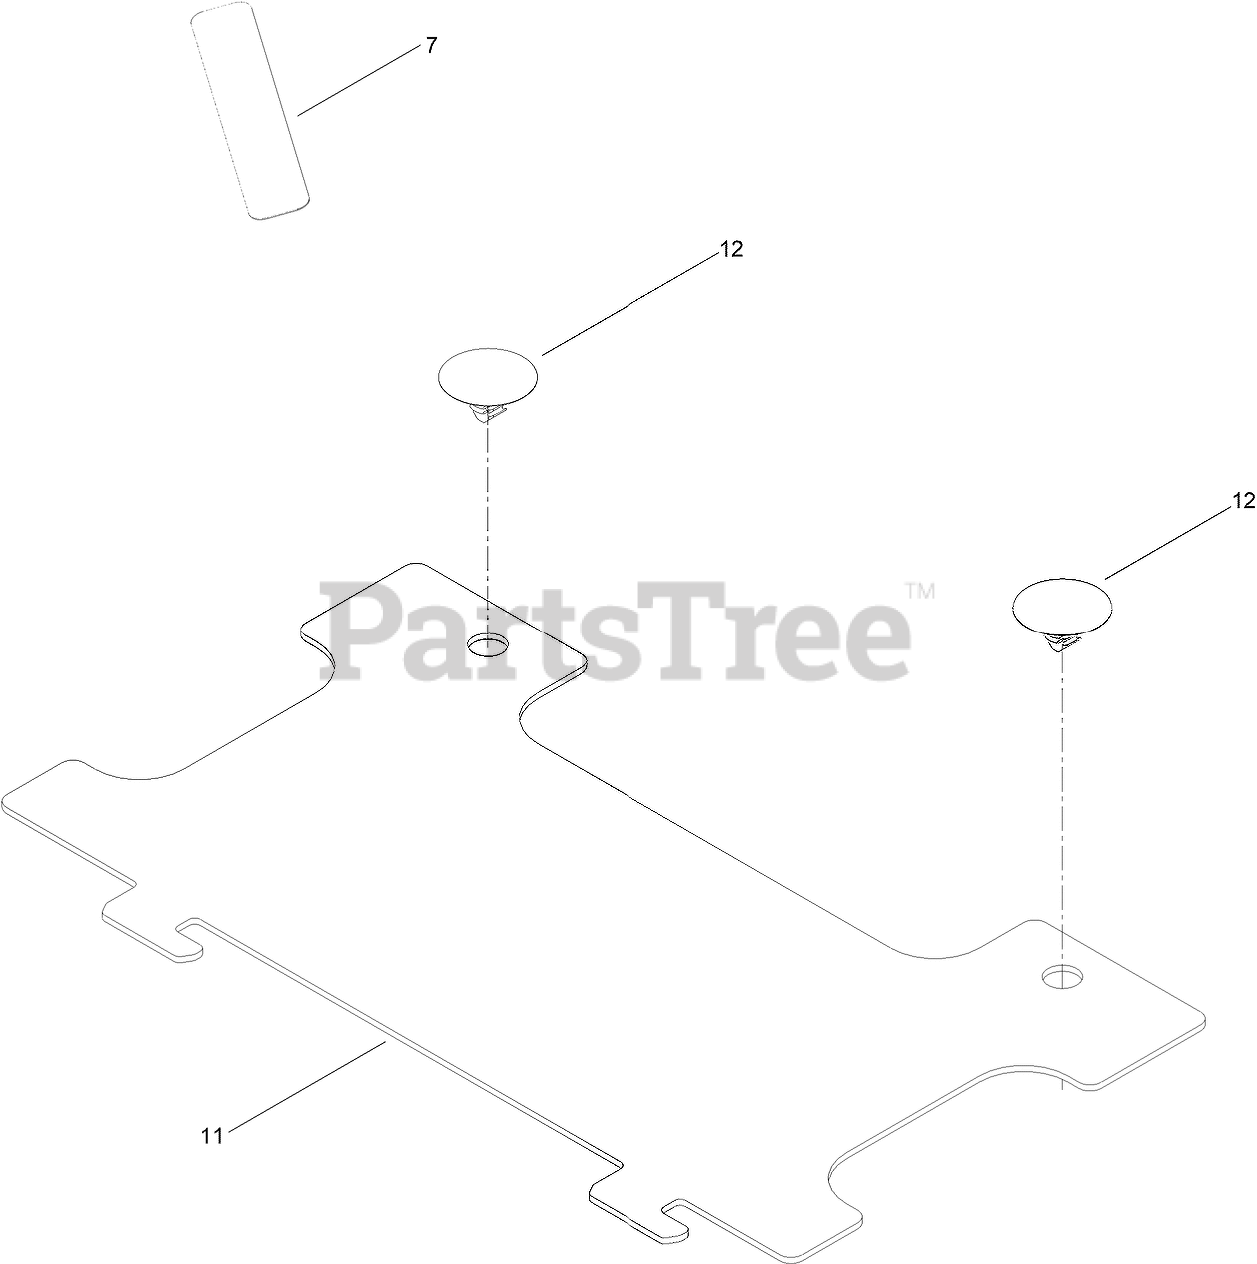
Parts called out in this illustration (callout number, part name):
7	DECAL-SHUTDOWN
11	SHIELD
12	RIVET-PLASTIC
